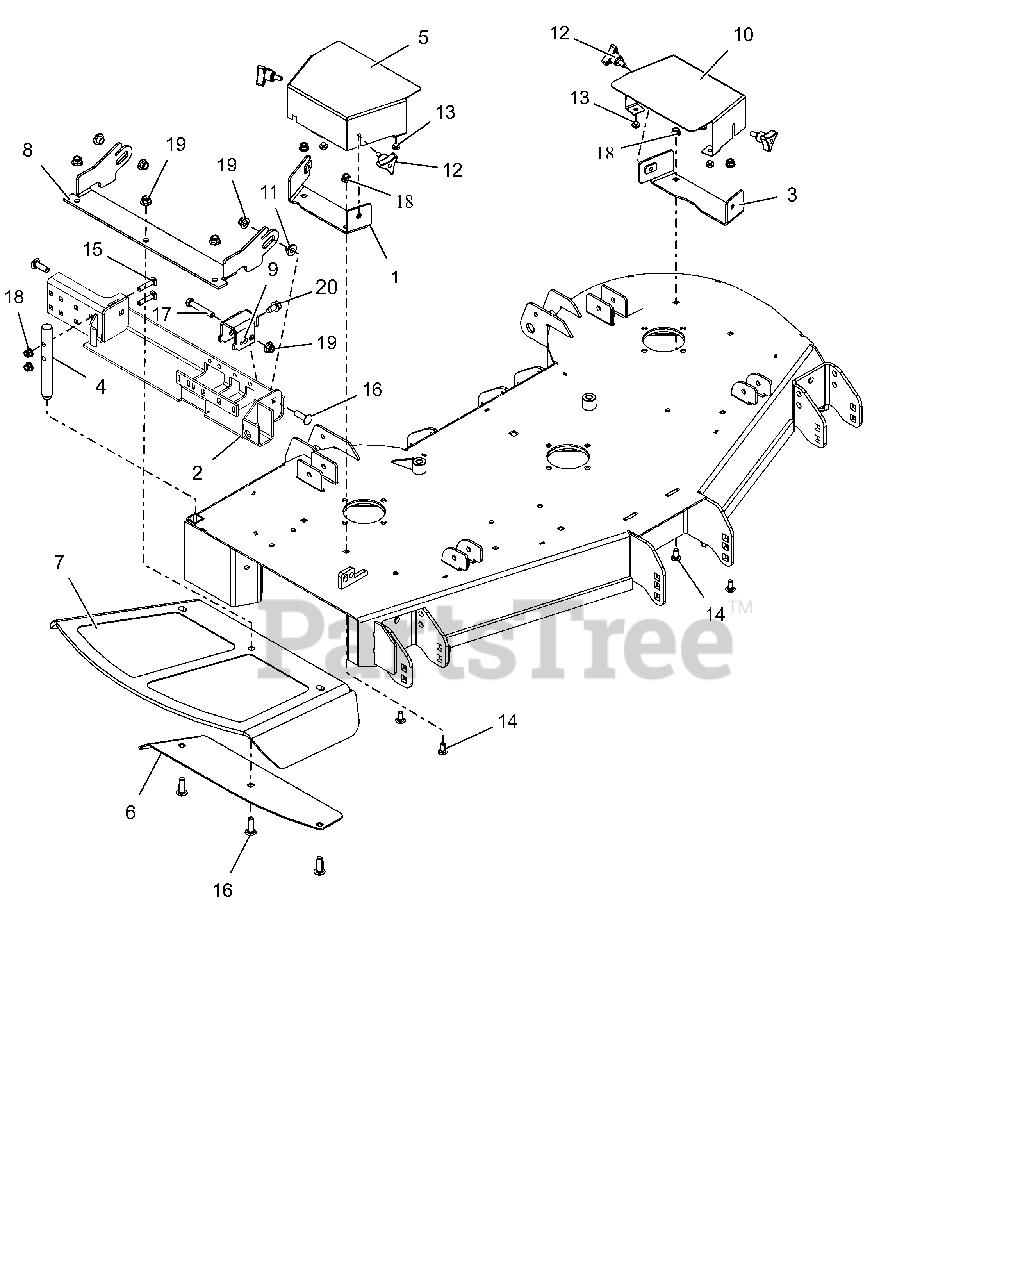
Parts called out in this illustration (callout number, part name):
1	BRKT, RH BELT GUARD MOUNTING
2	WLDMT, GRASS CATCHER
3	WLDMT, RH BRKT BELT GUARD MOUNTING (RED)
4	PIN, DISCHARGE CHUTE X-DRILLED
5	GUARD, RH DECK BELT
6	48-60 DISCH CHUTE CLMP PLT-BLK
7	CHUTE,48-60" FRMD RUBBER DISCH
8	BRKT, 48-60" CHUTE MTG
9	BRKT, DISCH. CHUTE MTG
10	GUARD, LH DECK BELT (RED)
11	BSHG-FLG .385X.500X.875X.406
12	KNOB,WING STUD 5/16-18 X .75
13	BUMPER GROMMET
14	@BLT-RDHDSQNK .31-18X.75 G5YZ
15	@BLT-RDHDSQNK .31-18X1.50 G5YZ
16	@BLT-RHDSSQNK .38-16X1.25 G5YZ
17	@BLT-HEX .38-16X2.25 GR5 YWZC
18	@NUT-LK-NYL-FLG .31-18 YWZC
19	@NUT-LK-NYL-FLG .38-16 YWZC
20	@SCR-TAP .38-16X.75 HWH TR YWZ
